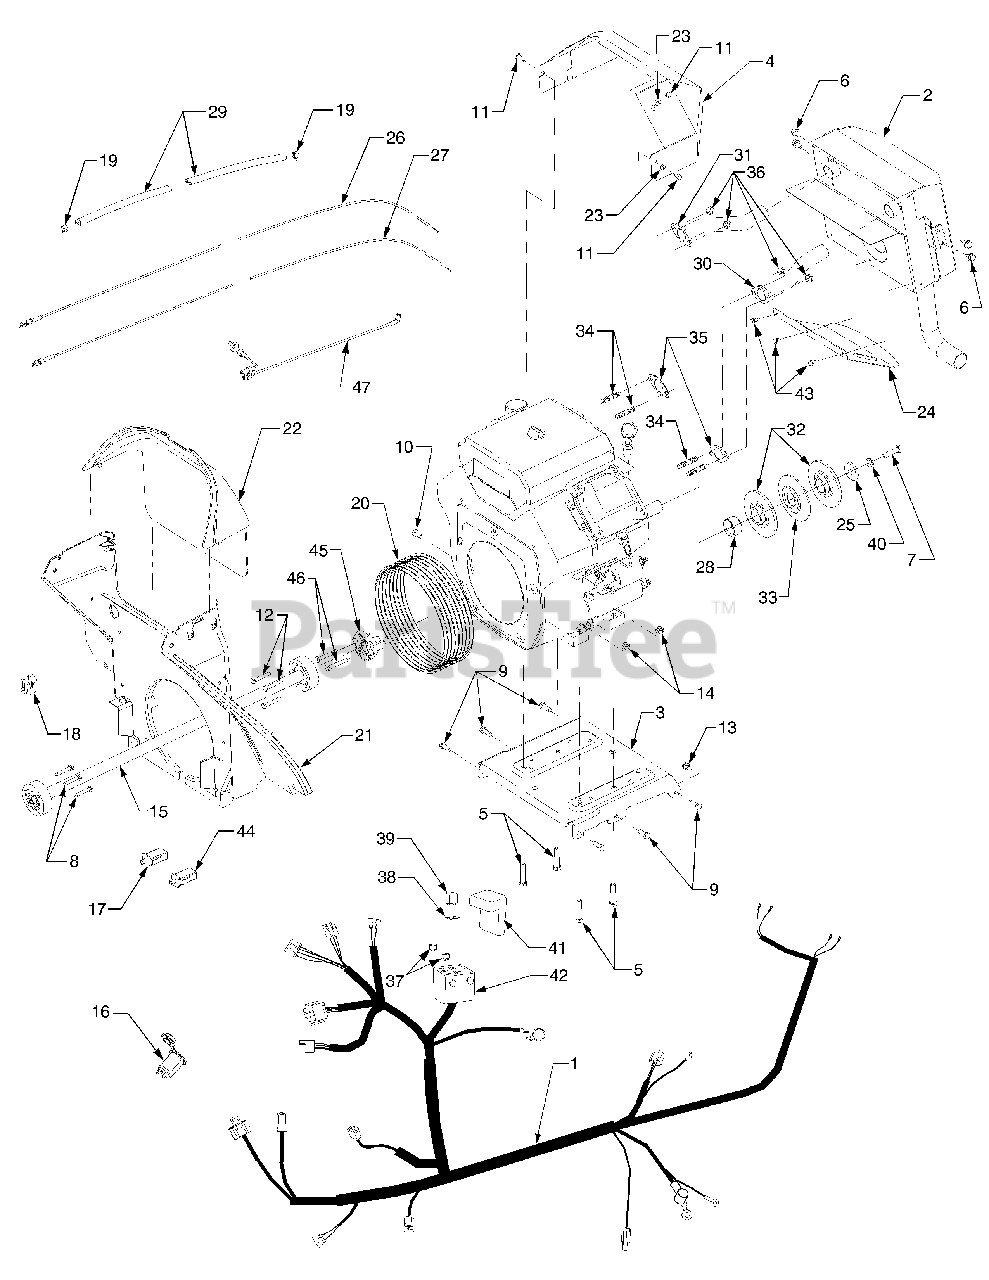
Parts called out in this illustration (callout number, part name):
1	Harness, Wire
2	Muffler Assembly
3	Plate, Engine Mounting
4	Shield, Muffler Heat
5	Screw, Hex Cap, 3/8-24 x 1.75 GR5
6	Screw, Hex Wash. Hd. Tapp 5/16-18 x .5
7	Screw, Hex Cap, 7/16-20 x 1.5 GR5
8	Screw, Hex Cap Lock 1/4-20 x 1.25 GR5
9	Screw, Hex Cap, 5/16-18 x .875 GR5
10	Screw, Hex Cap, 5/16 - 24 x .625 GR5
11	Screw, Hex Cap, M6 - 1.0 x 10MM
12	Screw, Hex Cap, Lock 1/4-20 x 1.62 GR5
13	Nut, Hex Insert Lock, 5/16-18
14	Nut, Hex Lock, 3/8-24
15	Shaft, Drive, 27.125 Long
16	Receptacle, 12V Power
17	Switch, Plunger (Reverse)
18	Switch, Snap Mount (Seat)
19	Clamp, Hose
20	Boot, Intake
21	Baffle, Lower Air
22	Baffle, Upper Air
23	Washer, Flat, .281 x .50 x .06
24	Shield, Lower Exhaust
25	Washer, Flat, .417 x 1.5 x .225
26	Cable, Throttle Control
27	Cable, Choke Control
28	Spacer, Crankshaft
29	Hose, Fuel Line
30	Pipe, Exhaust RH
31	Pipe, Exhaust LH
32	Pulley Half
33	Pulley, Center
34	Stud, M8 - 1.25 x 33MM
35	Gasket, Exhaust
36	Nut, Hex, M8 x 1.25
37	Fuse, 25 Amp
37	Fuse, 5 Amp
38	Gasket, Silicone
39	Relay
40	Washer, Lock, 7/16
41	Cover, Fuse Box
42	Box, Fuse
43	Screw, Hex Wash. Hd. Tapp, #12-24 x .38
44	Switch, Plunger (Brake)
45	Adapter, Drive Shaft
46	Screw, Hex Flange, M10 x 1.5 x 90
47	Hose, Vacuum
